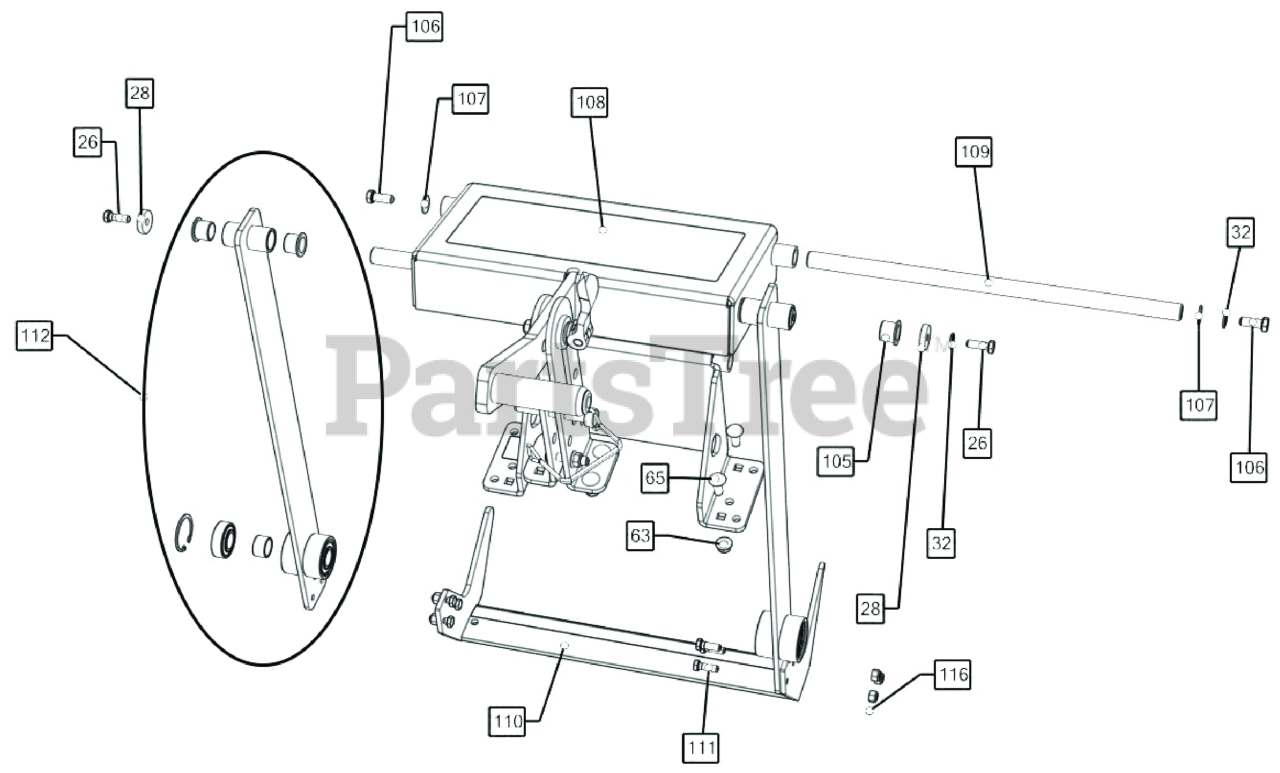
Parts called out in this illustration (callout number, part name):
26	SCREWCAP 5/16"-18 X 1" HCS ZP
28	WASHER 1.125 OD X 0.344 ID X .25 THK ZP
32	WASHER, BELLEVILLE CONTACT .323X.717X.05
63	NUT-HEX-NYLK, FLG .375"-16 ZP
65	BOLT CARRAIGE 3/8-16 X 1" ZP
105	BUSHING PIVOT FRAME AE
106	SCREWCAP 3/8"-16 X 1" HCS ZP
107	WASHER 5/16" FLATWASHER Z/P
109	SHAFT PIVOT DEPTH
110	KIT BLADE 18" INCLUDES HARDWARE
112	ARM, BLADE SC181H ASSY
